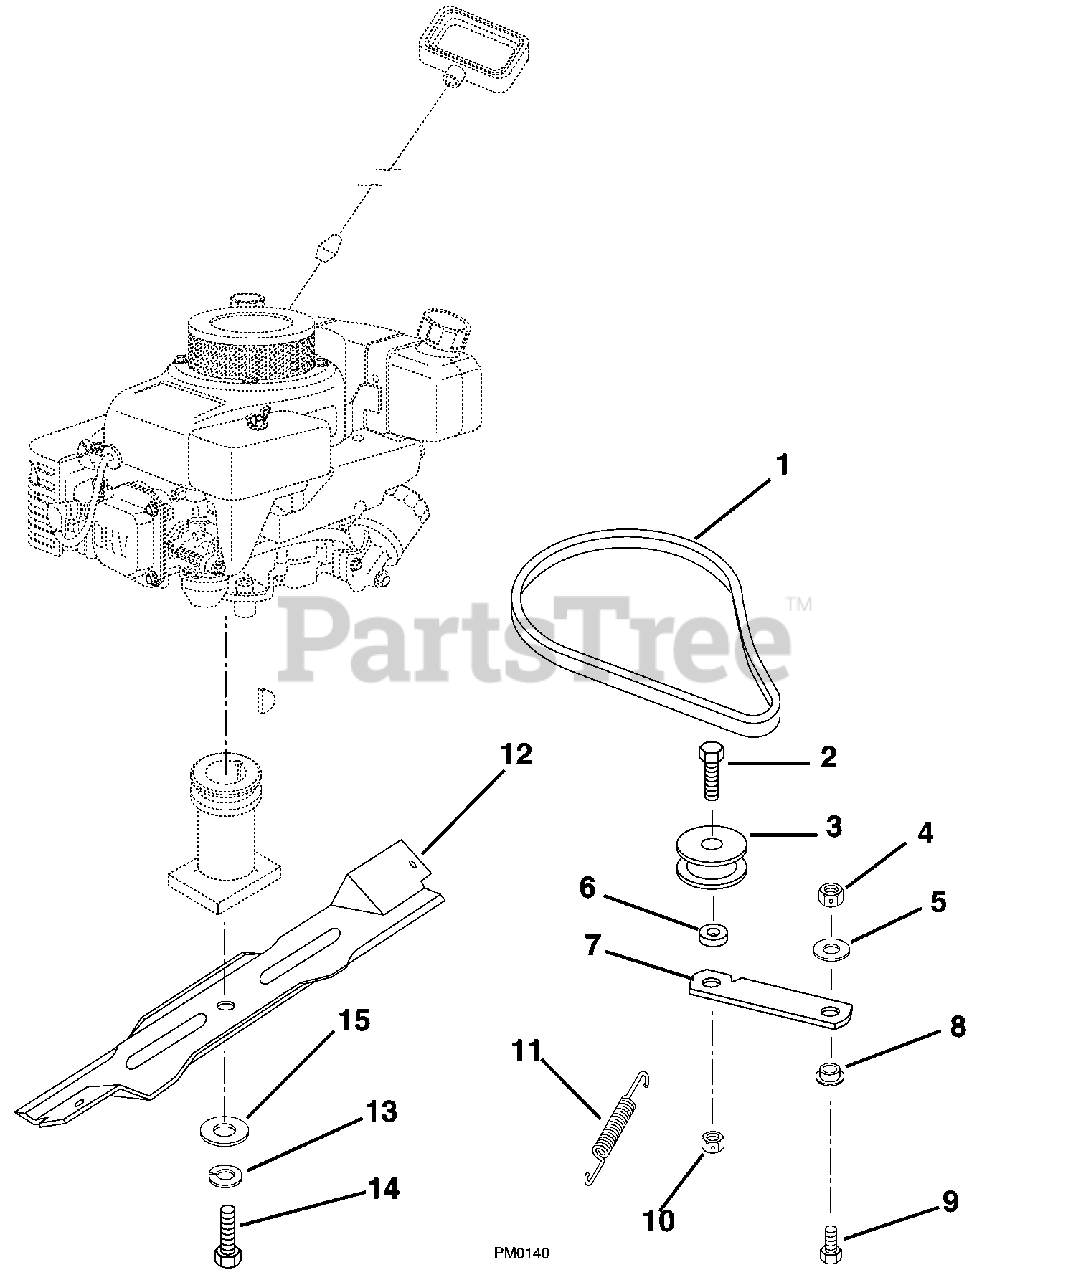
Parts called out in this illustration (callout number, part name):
1	V-Belt 3L Section
2	Bolt-Hex .44-14 x 1.25 Grade 5
3	Idler-Flat 1.75 x .47
4	Nut-Locking-Center .31 -18
5	Washer-Flat-Steel .323 x .625 x .062
6	Spacer .52 x .45 x .34
8	Bushing-Flange .325 x .501 x .250 x 1.120
9	Bolt-Hex .31-18 x .75 Grade 5
10	Nut-Locking-Center .44-14
11	Spring, Tension .043 x .44 x 3.31
12	Blade, 21" Mower
13	Washer-Locking .38 x .094
14	Bolt-Hex .38-24 x 2.00
15	Washer-Flat Steel .390 x 1.50 x .125 (600 C)
